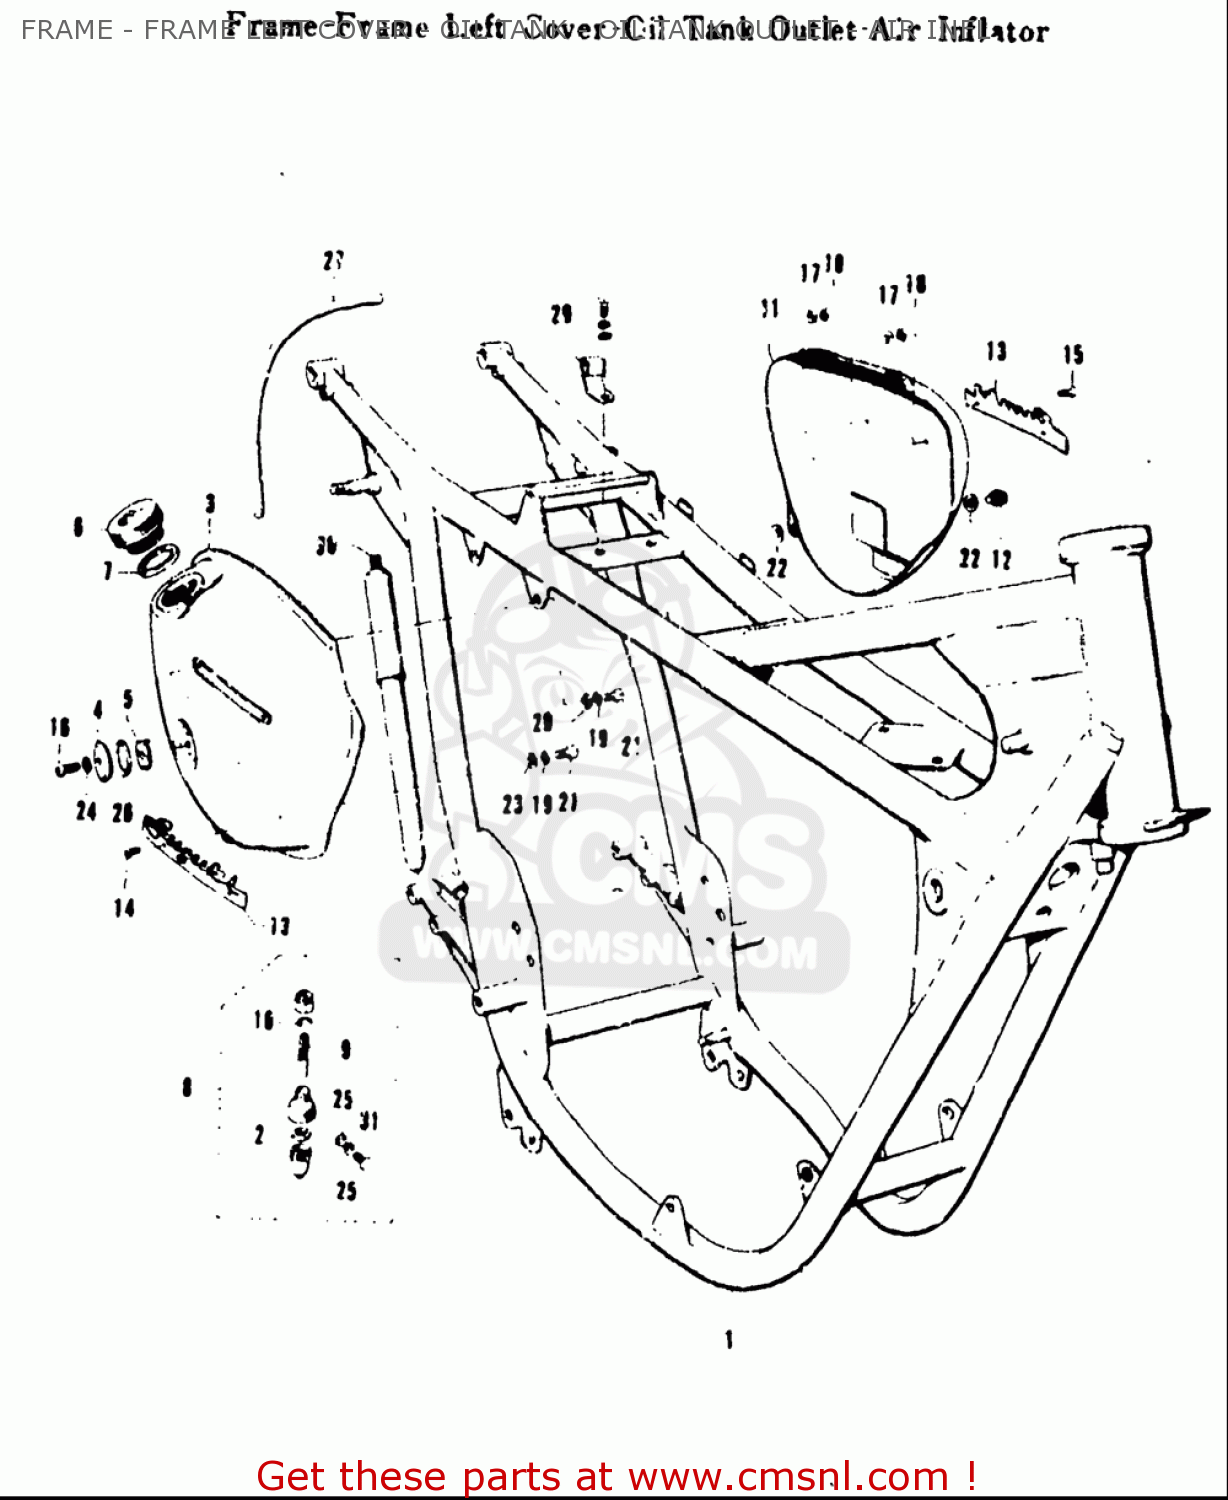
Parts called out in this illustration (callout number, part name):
5	LENS SET,OIL INSPECTION
6	CAP,OIL TANK
7	GASKET,OIL TANK FILLER CAP (NAS)
9	UNIT,OIL FILTER
10	GASKET,OIL OUTLET JOINT (NAS)
14	SCREW
17	NUT
18	WASHER,LOCK
19	WASHER,LOCK
20	WASHER
21	BOLT(6X14)
22	NUT
24	GASKET(5X9.5X1) (NAS)
25	GASKET(6.2X11X1).2 (NAS)
26	O RING(D:3,ID:23)
27	HOSE(5X8X2000)
28	UNION BOLT
